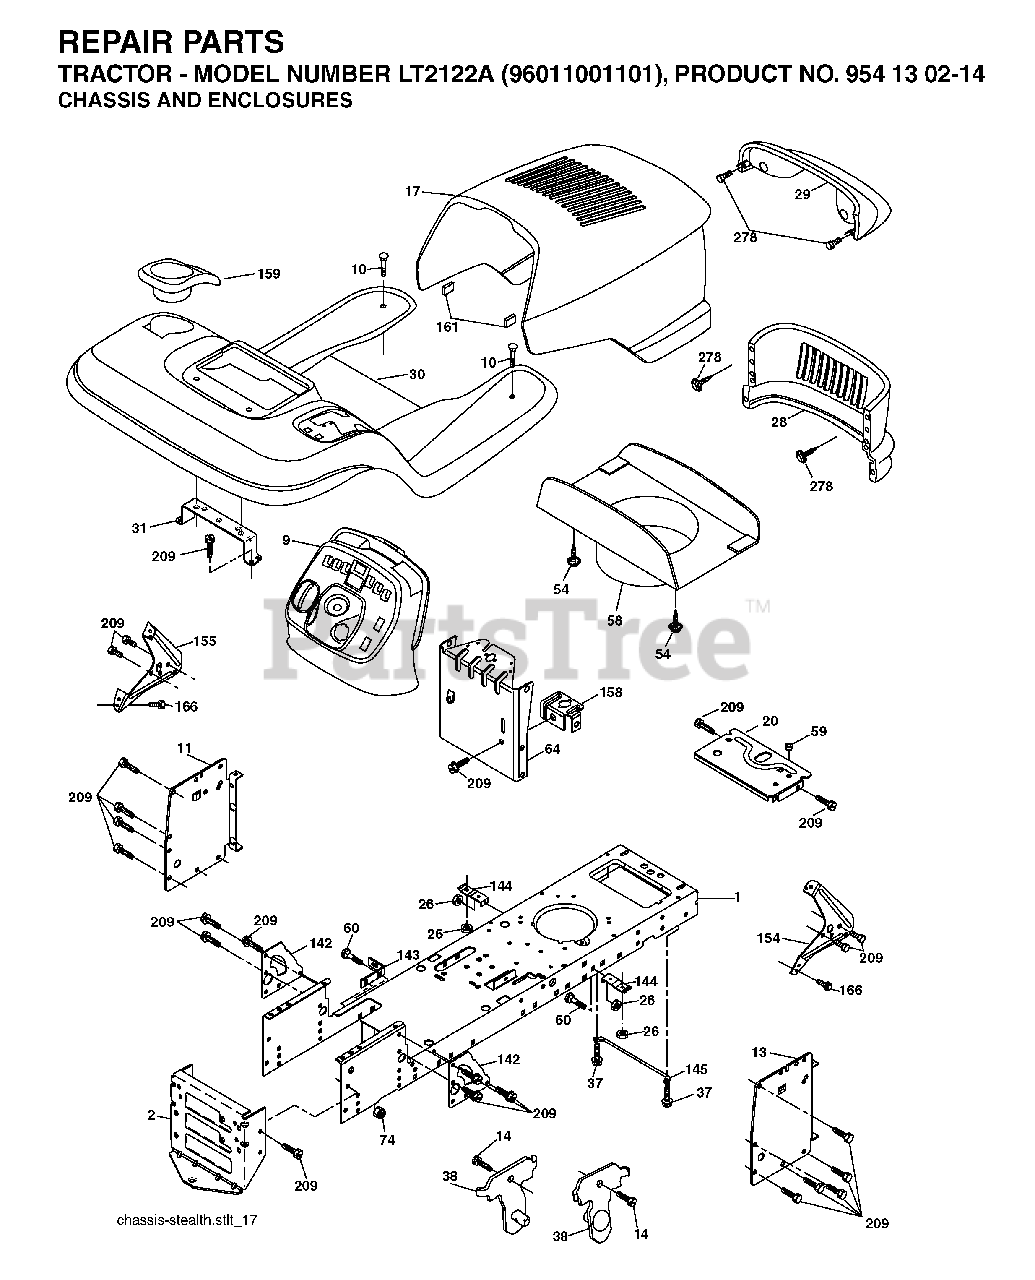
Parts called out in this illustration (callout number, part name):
1	CHASSIS STAMPING
2	DRAWBAR, 12GA
10	BOLT D
13	PANEL DASH RH
26	NUT
38	BRACKET.ASM.PIVOT.MOWER.REAR
58	DUCT HOOD
59	BUSHING.1.375OD
64	DASH LOWER
74	LOCKNUT
142	PLATE REINFORCEMENT
143	BRACKET, SWAYBAR CHASSIS
144	BRKT, FOOT REST
145	ROD PIVOT CHASSIS/HOOD
161	EXTRUSION BUMPER
209	SCREW, 3/8-16X3/4
278	SCREW
